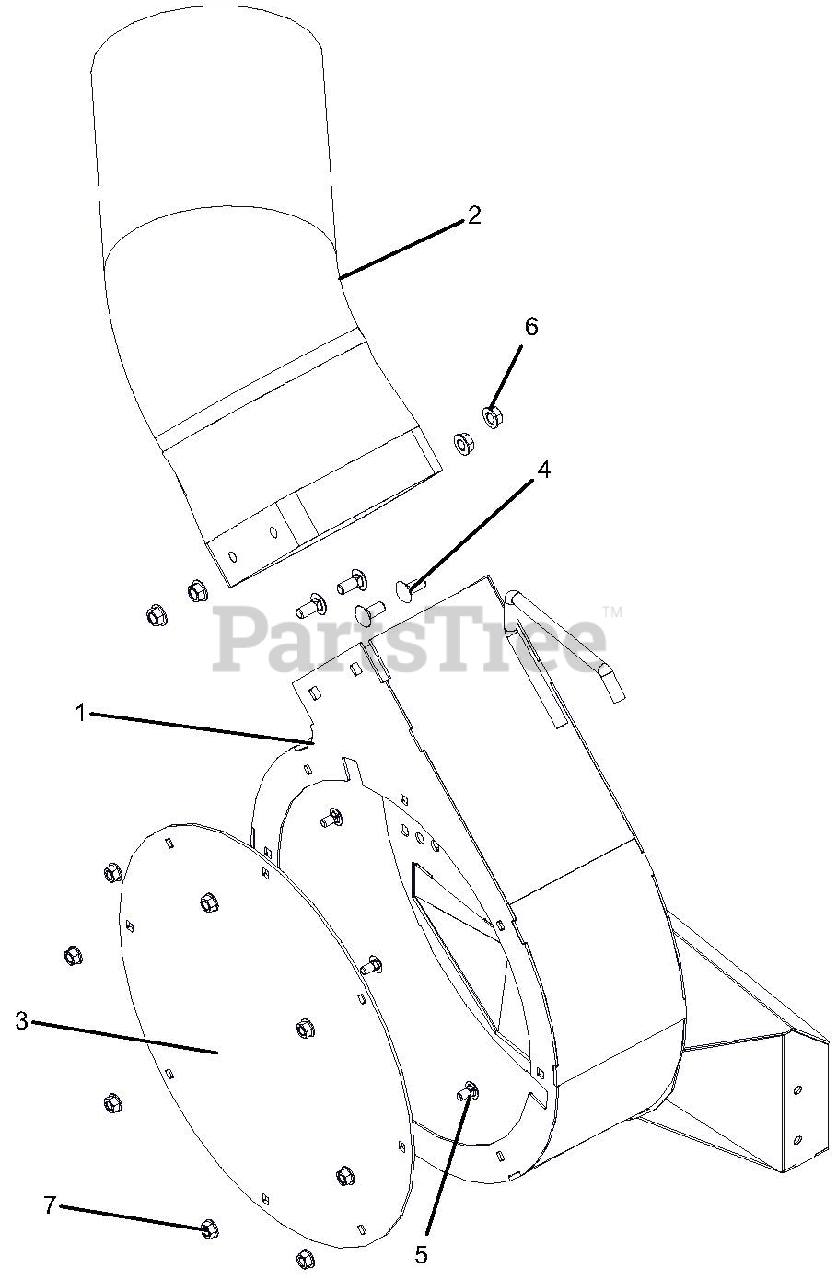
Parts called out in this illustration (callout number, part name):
1	WLDMT, HOUSING BLOWER W/DECALS
2	ADAPTOR, HOSE
3	COVER, HOUSING
4	BLT-RDHDSQNK .31-18X.75 G5 YWZC
5	BLT-RDHDSQNK .25-20X.50 G5 Y
6	NUT, LK-TOP-FLG .312-18 YWZC
7	NUT, LK-TOP-FLG .25-20 YWZC
